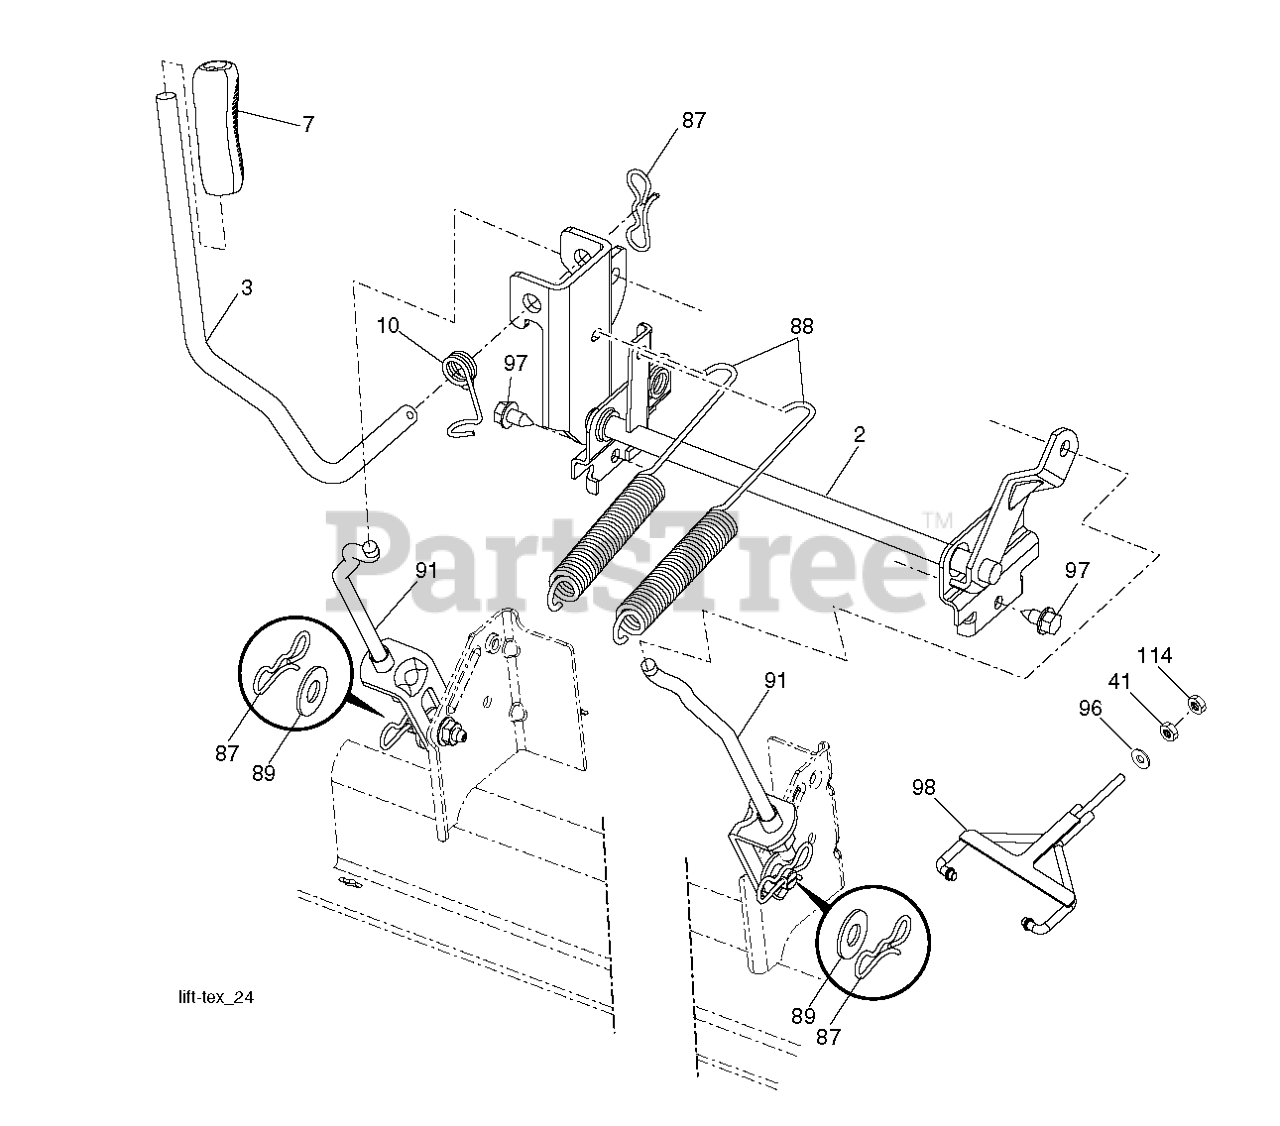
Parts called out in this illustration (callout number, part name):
2	SHAFT.ASM.CROSS.LIFT
3	LEVER.LIFT.HANDLE.GT
7	GRIP.HANDLE.LIFT.PVC.BLACK
10	SPRING.TORSION.LIFT.HANDLE
41	NUT, LIFT LINK 7/16-20
87	PIN.COTTER.7/16.BOW TI.
88	SPRING.LIFT.ASSIST.GT2
89	WASHER.CLEAR.ZINC
91	LINK.ASM.LIFT.54"TG
96	BUSHING SPHERICAL SUSP. FRONT
97	SCREW, 3/8-16X3/4
98	SUSPENSION WLDT FRONT DECK
114	NUT **
